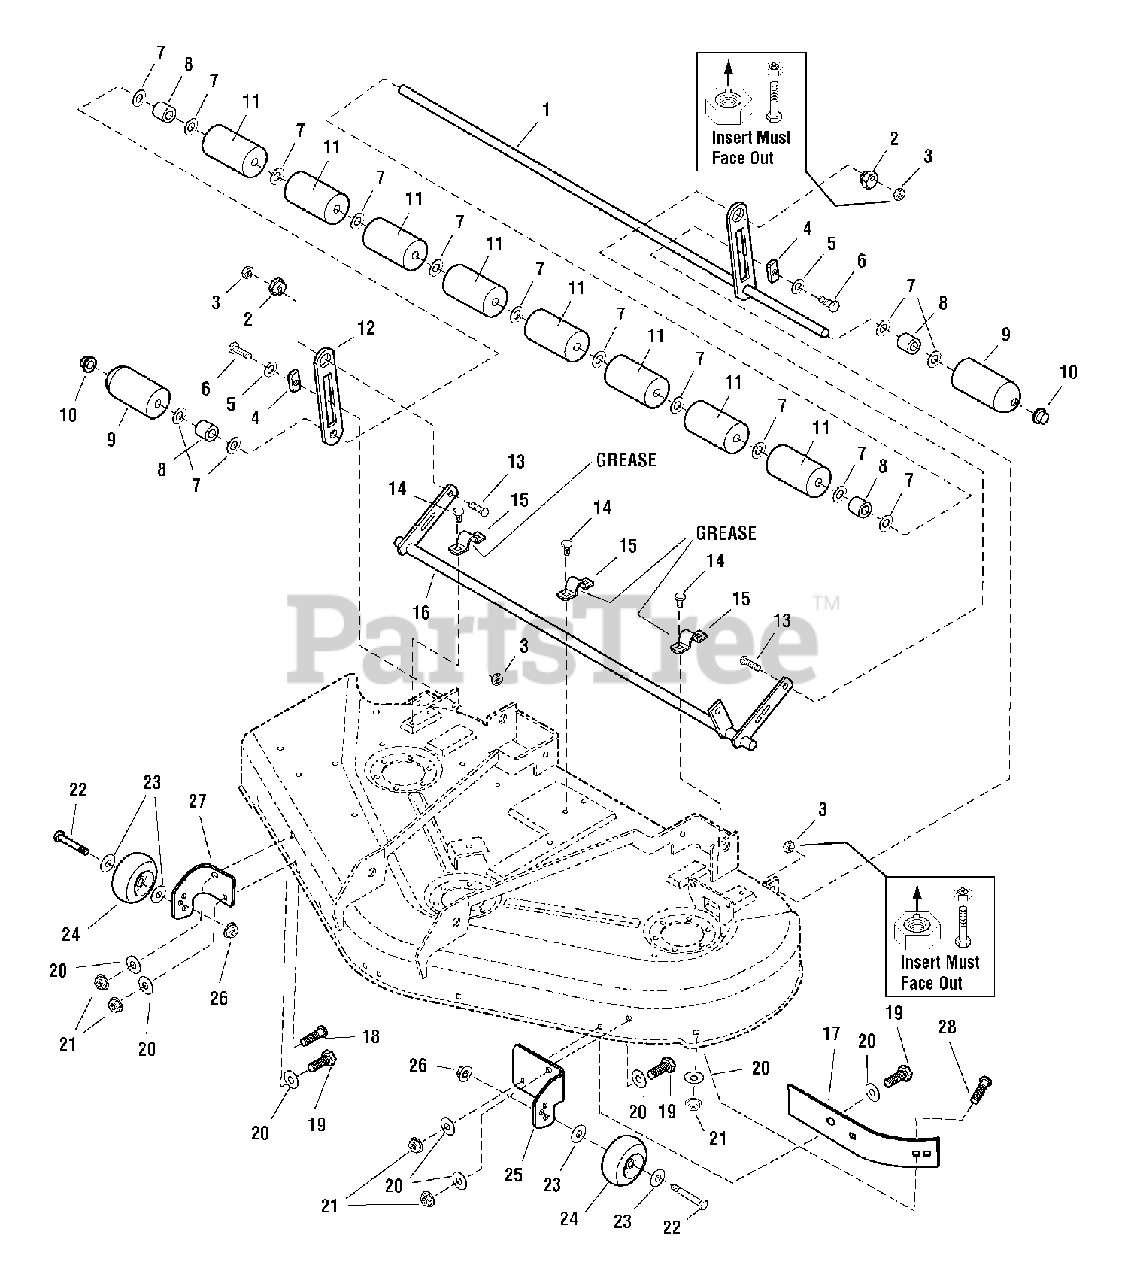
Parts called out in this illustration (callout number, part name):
1	SHAFT, ROLLER, 50"
2	NUT, ADJUSTER
3	NUT, HEX ALUMINUM INSERT LOCK, 3/8-16
4	SLIDE
5	WASHER, PLAIN, 1/2
6	BOLT, SHOULDER, 3/8-16
7	WASHER, .661 ID X 1.12 OD X .11, BLACK
8	SPACER, 0.666 ID X 0.876OD X 1.25 LG SPLIT BLK
9	ROLLER, ROUNDED
10	NUT, PUSH
11	ROLLER
12	BAR, ROLLER
13	CARRIAGE BOLT, 3/8-16 X 1-1/2
14	CAPSCREW, HEX HEAD TAPTITE, 5/16-18 X 3/4
15	STRAP
16	SHAFT, DECK LIFT, 50"
17	SHORT BLOWOUT BAFFLE
18	CARRIAGE BOLT, 5/16-18 X 1
19	CAPSCREW, HEX HEAD,5/16-18 X 1
20	WASHER, 5/16, PLAIN, SAE
21	NUT, 5/16-18, HEX, NYLON LOCK
22	BOLT, REAR WHEEL
23	WASHER
24	GAUGE, WHEEL
25	BRACKET, GAUGE WHEEL, LH
26	NUT, FLANGE, SIDELOCK, 3/8-16
27	BRACKET, GAUGE WHEEL, RH
28	CARRIAGE BOLT, 5/16-18 X 3/4
